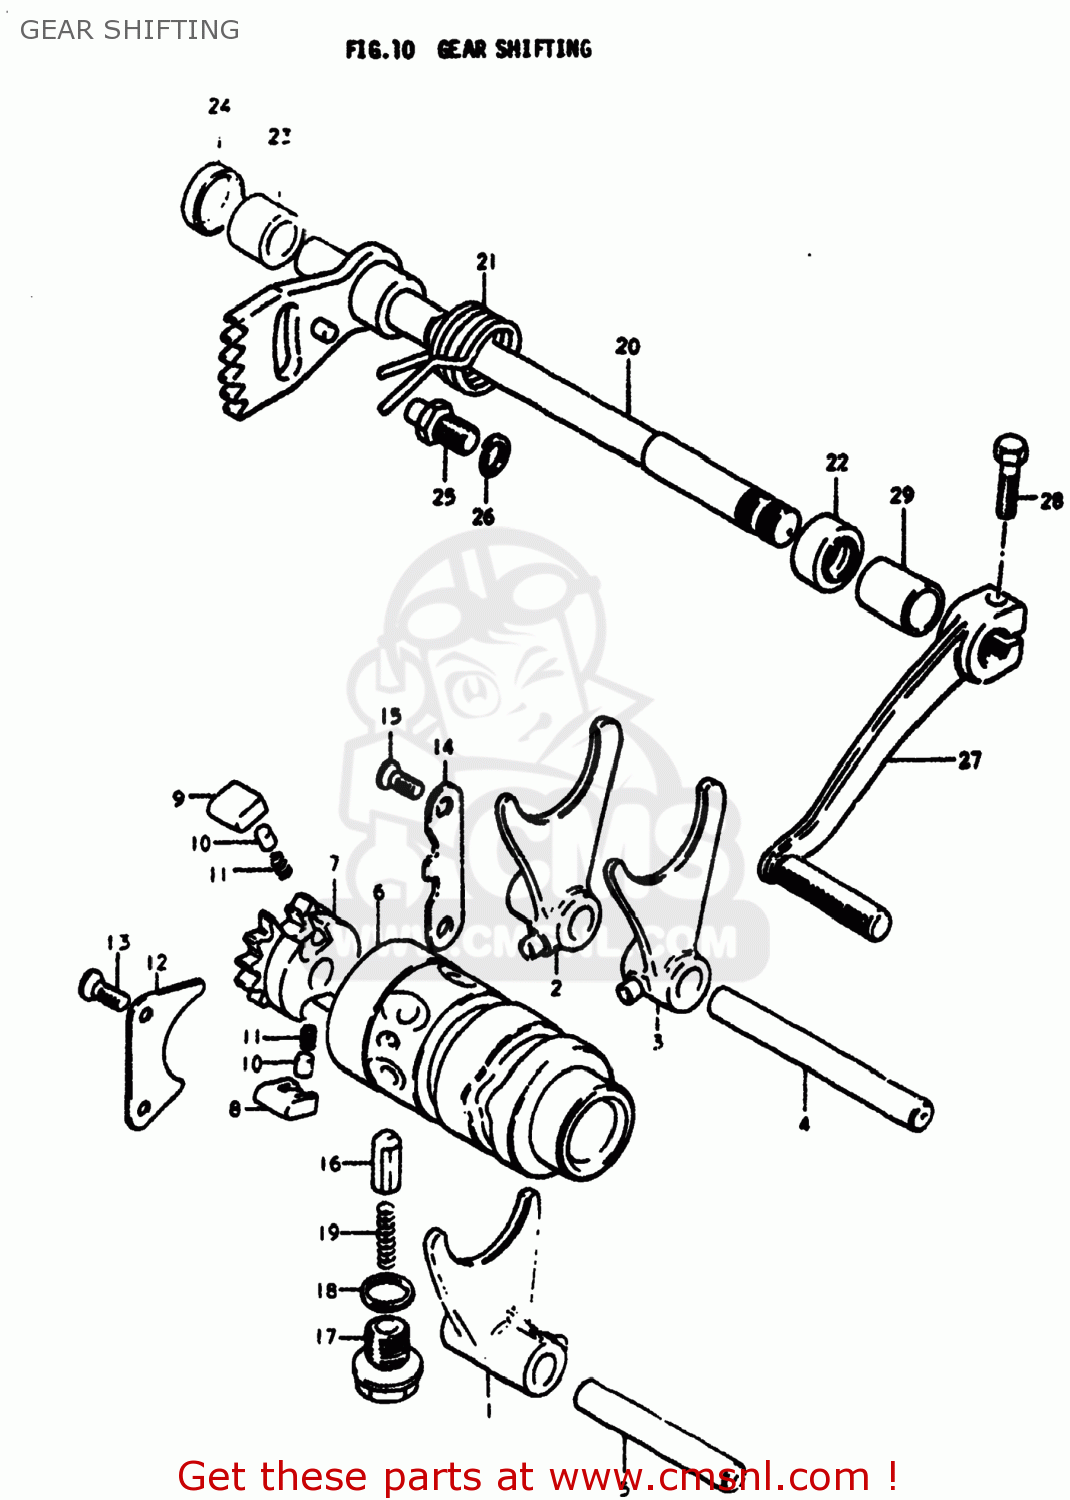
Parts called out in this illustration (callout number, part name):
1	FORK,GEAR SHIFT NO.1
2	FORK,GEAR SHIFT NO.2
3	FORK,GEAR SHIFT NO.3
4	SHAFT,GEAR SHIFT FORK
5	SHAFT,GEAR SHIFT FORK
6	CAM,GEAR SHIFT
7	RETAINER,GEAR SHIFT CAM
8	PAWL,GEAR SHIFT NO.1
9	PAWL,GEAR SHIFT NO.2
10	PIN(5X8)
11	SPRING
12	LIFTER,GEAR SHIFT PAWL
13	SCREW
14	STOPPER,GEAR SHIFT POLE
15	SCREW
16	STOPPER,GEAR SHIFTING
17	BOLT,GEAR SHAFT CAM STOPPER
18	GASKET(14X19.2X2) (NAS)
19	SPRING
20	SHAFT,GEAR SHIFT
21	SPRING
22	OIL SEAL
23	SPACER (12.2X20X13)
24	PLUG
25	STOPPER,GEAR SHIFT CAM
26	LOCK WASHER
27	LEVER ASSEMBLY,GEAR SHIFTING
28	BOLT
29	CUSHION
